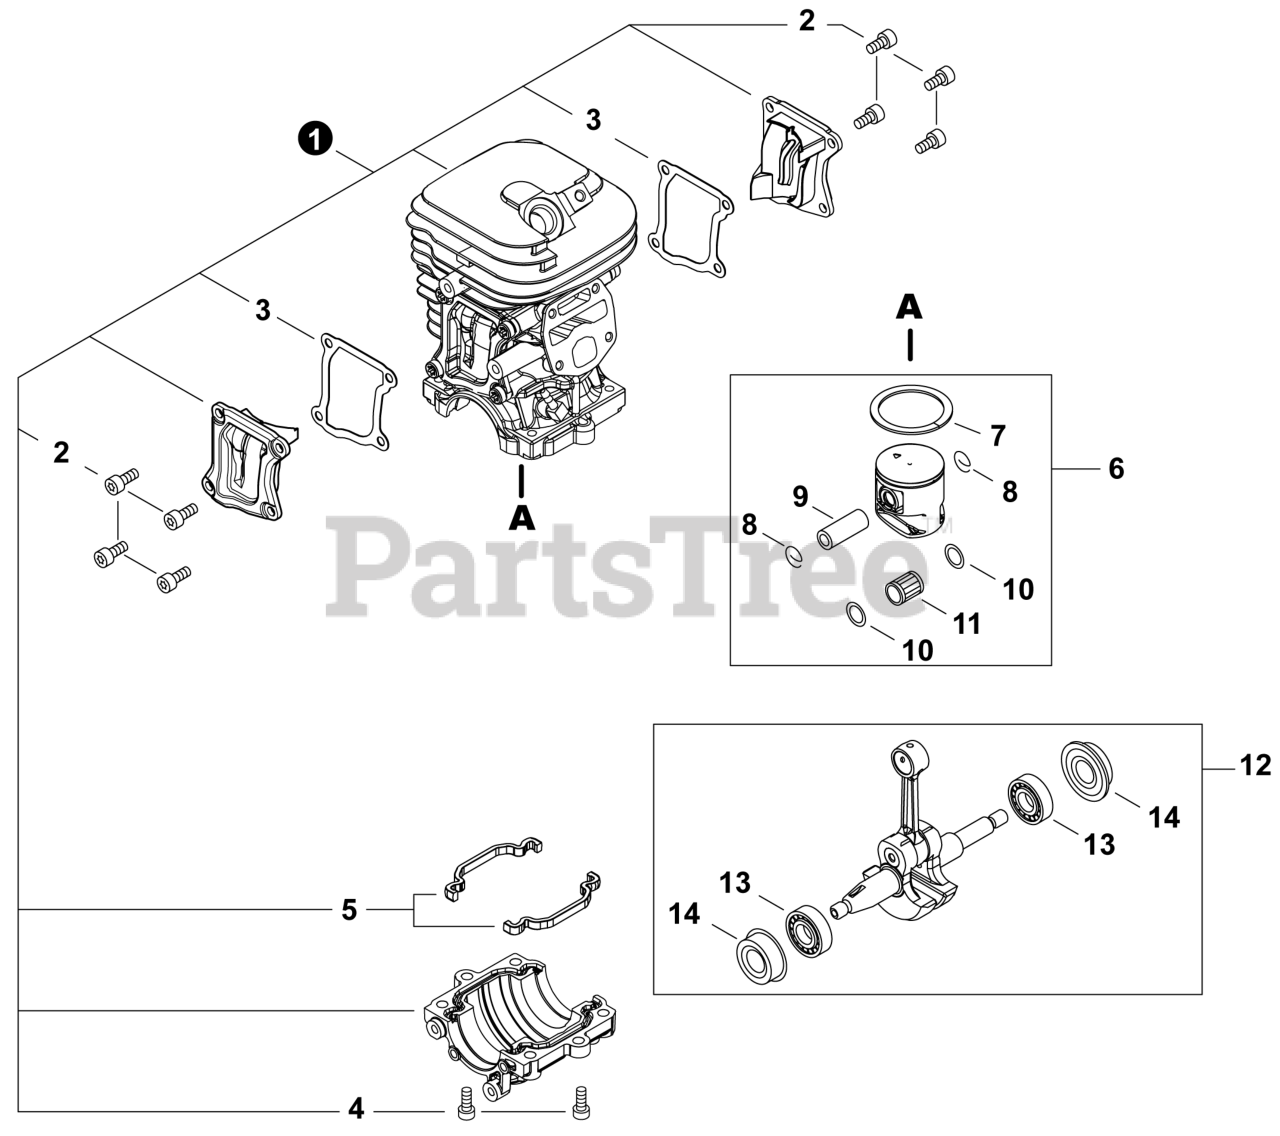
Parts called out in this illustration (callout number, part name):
1	CRANKCASE SET
2	BOLT, TORX 4x10
4	BOLT, TORX 5x16
5	SEAL KIT
6	PISTON KIT
7	RING, PISTON
8	RING, SNAP 10
9	PIN, PISTON
10	WASHER, THRUST 10
11	BEARING, NEEDLE
12	CRANKSHAFT ASSY
13	BEARING, BALL 6202
14	SEAL, OIL
